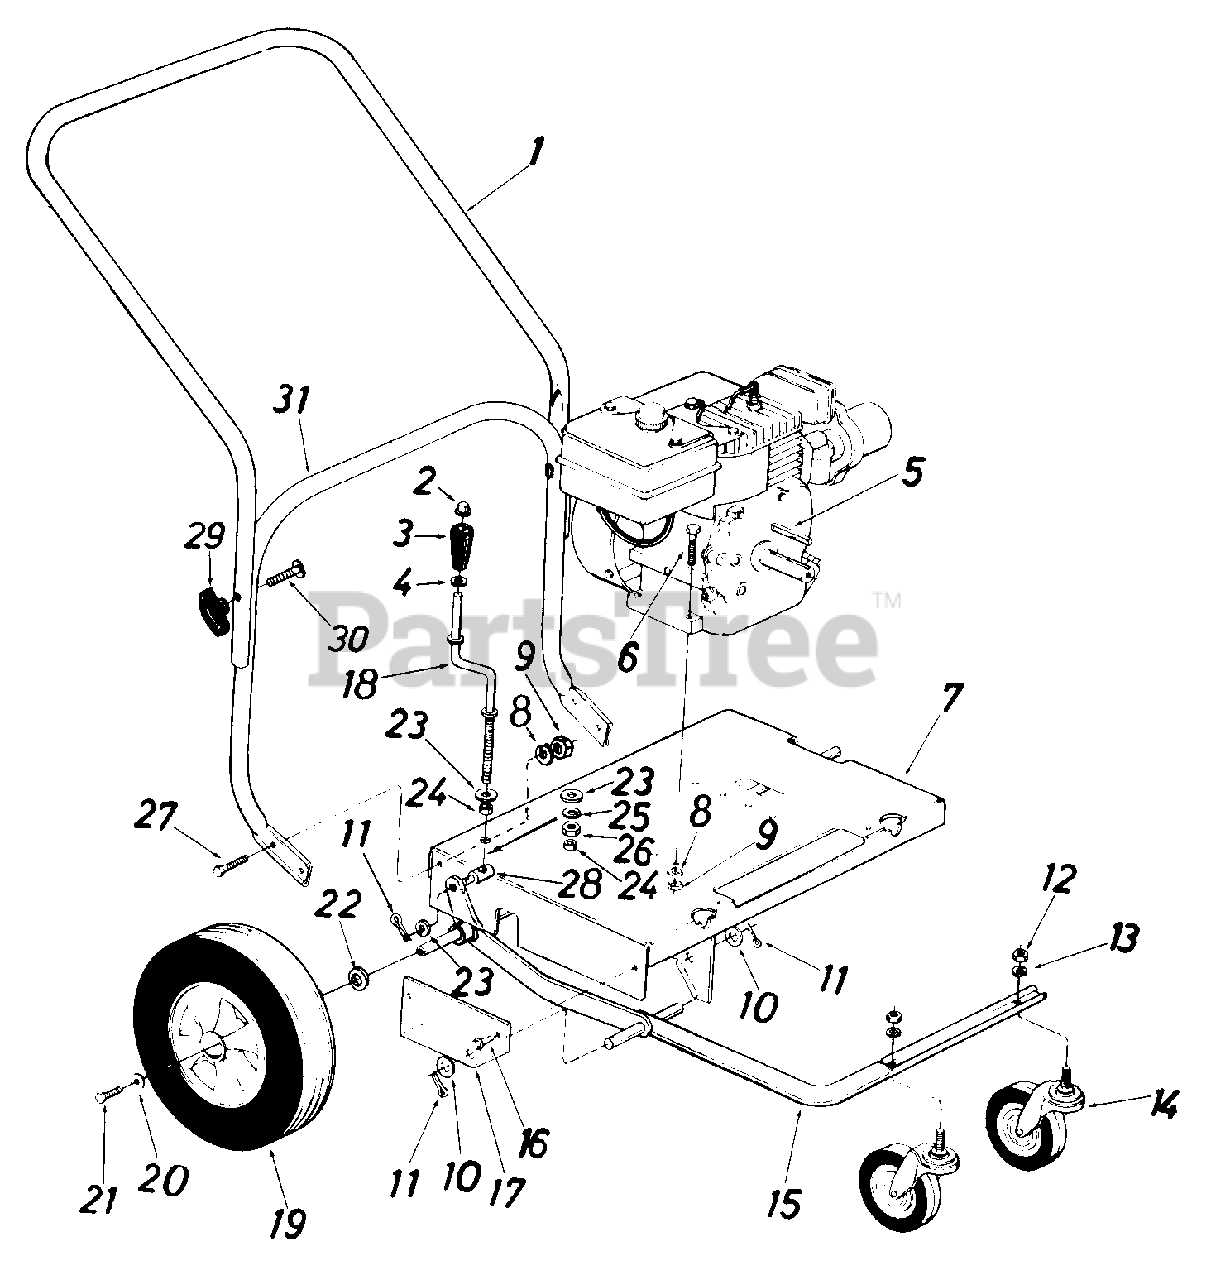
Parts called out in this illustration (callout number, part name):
1	Upper Handle
2	Push Nut 3/8" Rod
3	Crank Knob
4	Fl.-Wash. .385" I.D. x .62" O.D.
5	Sq. Key 1/4" x 2.0" Lg.
6	Hex Bolt 5/16-18 x 1.50" Lg.
9	Hex Nut 5/16-18 Thd.
10	Fl.-Wash. .63" I.D. x 1.25" 0. D.
11	Cotter Pin 1/8" Dia. x 1.0" Lg.
12	Hex Nut 1/2-13 Thd.
13	L.-Wash . 1/2 " I.D.
14	Swivel Caster Wheel 5" Dia. x 1.25"
19	Wheel Ass'y. Comp. 12" x 3" (Plastic)
20	Fl.-Wash. 34" I.D. x .87" O.D.
21	Hex Locking Bolt 5/16-24 x .62" Lg.
22	Fl.-Wash.
23	Fl.-Wash. .38" I.D. x .57" 0.D.
24	Spacer .382" I.D. x .50" O.D. x .180" Lg.
25	L.-Wash. 3/8" I.D.
26	Hex Nut 3/8-8 Thd.
27	Hex Bolt 5/16-18 x .75" Lg.
28	Ferrule
29	Hand Knob
30	Carriage Bolt 5/16-18 x 2.0" Lg.
31	Lower Handle
